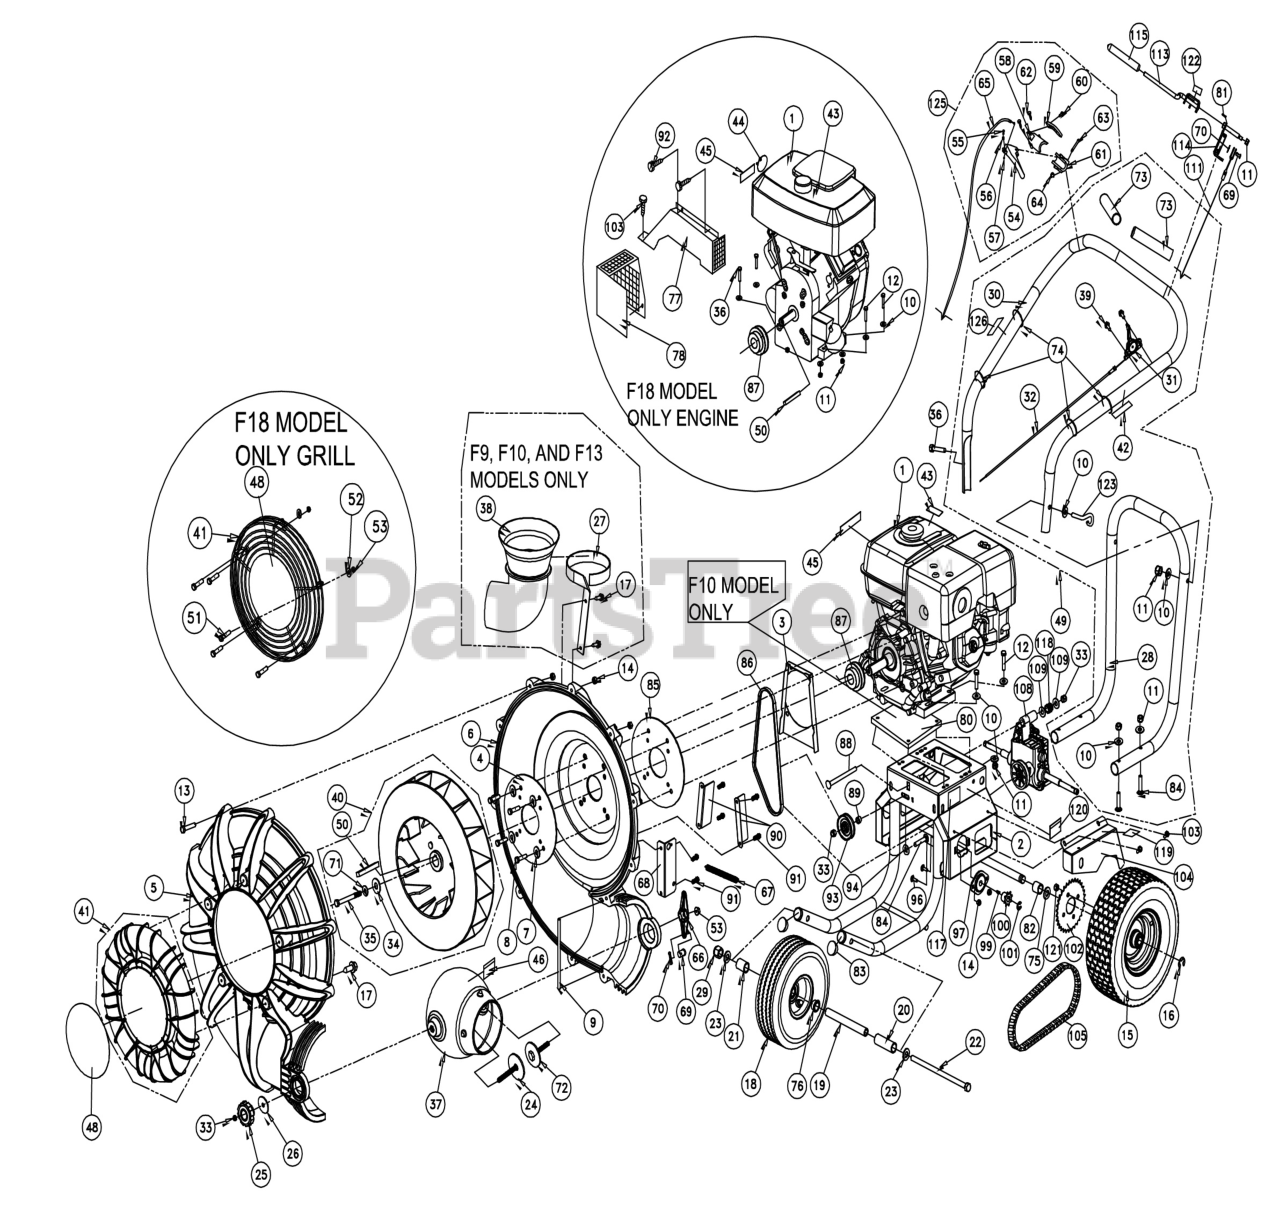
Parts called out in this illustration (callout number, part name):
1	ENGINE HONDA 10PH VANGUARD
2	FORCE FRAME W/LABELS KIT
3	GUARD BELT UPPER FSP
4	SEE: 440330
5	HOUSING FRONT MOLDED
6	HOUSING BACK MOLDED
7	WASHER LOCK 7/16" S/T MED
8	SCREWCAP 3/8"-16X2" HCS ZP
9	ROD HAND STOP
10	WASHER 5/16" FLATWASHER Z/P
11	NUT LOCK 5/16"-18 HEX Z/P
12	SCREWCAP 5/16"-18X2 1/2" HCS ZP
13	SCREWCAP 1/4"-20X1 1/2" HCS ZP
14	NUT WHIZ 1/4"-20 WASH FACE
15	WHEEL & TIRE 13" X 5" PNEU SPROCKET
16	RING RETAINING "E" 3/4"
17	SCREW SM 1/4"X3/4" TYPE A HX WF
18	WHEEL ASSY PNEUMATIC
19	SPACER AXLE FRONT
20	SPACER LH WHEEL FRONT
21	SPACER RH WHEEL FRONT
22	SCREWCAP 1/2"-13 X 9 1/2" HCS ZP
23	WASHER 1/2" SAE Z/P
24	WASHER W/BOLT WA
25	KNOB 3/8-18, SOLID HUB
26	WASHER 2.25 OD X .515 ID X .134 ZP
27	BRACKET EXHAUST FRONT
28	HANDLE LOWER
29	NUT LOCK 1/2"-13 NYLON INSERT
30	HANDLE UPPER
31	CONTROL THROTTLE BLOWER
32	CABLE THROTTLE BLOWER
33	NUT LOCK 3/8-16 LT WT THIN ZP
34	WASHER 1.5 OD X 0.453 ID X 0.5
35	SCREWCAP 7/16-20 X 3 1/2 GR. 8 W/ PATCH
36	SCREWCAP 5/16"-18X2" HCS ZP
37	DIRECTOR CONE 4" W/LABEL
38	DIVERTER FRONT 4" (NEW STYLE)
39	SCREW SELFTAP #10-24 X 3/8"ZP
40	IMPELLER SERVICE KIT FORCE
41	GRILL KIT GEN II
42	LABEL THROTTLE CONTROL
43	LABEL HOT ENGINE
45	LABEL SAFETY PROTECT READ MANUAL
46	LABEL DANGER FLYING DEBRIS
48	LABEL FORCE GEN II SP
49	SEE: 440104-S
50	KEY 1/4" SQ X 3 1/4"
53	NUT LOCK 1/4"-20 HEX Z/P
54	LEVER DIVERTER
55	PIN LATCH DIVERTER
56	SPRING COMPRESSION 0.281 X 0.88
57	RING RETAINING 3/16" E-CLIP
58	SADDLE LOWER DIVERTER
59	PLATE LOCK DIVERTER
60	SCREW PLASTITE #6-19 X 5/8" HWH ZP
61	SADDLE UPPER DIVERTER
62	SCREW PLASTITE #10-14 X 1" HWH ZP
63	PIN PIVOT DIVERTER CONTROL
64	RING RETAINING 5/16"
65	CABLE DIVERTER
66	DIVERTER REMOTE ADAPTER
67	SPRING EXTENSION .468 X 5.25
68	BRACKET DIVERTER FORCE
69	PIN CLEVIS 1/4" X .75"
70	PIN CLIP HITCH 0.051 X 3/4"
71	WASHER LOCK 7/16" S/T MED
72	ADAPTOR MOUNT WA
73	GRIP 1-1/4" ID X 9.5" LONG
75	WASHER .765" ID X 1.25 OD X .06"
76	FORCE WHEEL BEARING .751 ID
80	SPACER PLATE WELDMENT
81	PIN ROLL 1/8" X 1/2" Z/P
82	SPACER REAR WHEEL SP
83	PLUG TUBE INSERT 1.25" O.D.
84	BOLT CARRIAGE 3/8"-16 X 1 3/4" ZP
85	PLATE ENGINE SPACER
86	BELT FORCE SP
87	SPACER HUB 1" ID X 1.25" W/PULLEY
88	BOLT CARRIAGE 3/8-16 X 5" ZP
89	TUBE SPACER 0.625" OD X 0.357" LONG
90	GUARD BELT LOWER FSP
91	SCREW PLASTITE 1/4-10 X 3/4 HWH ZP
93	PULLEY V IDLER 2.5
94	WASHER 1.00" OD X 0.380 SQ HOLE
96	BOLT CARRIAGE 1/4" X 3/4"
97	SEE: 891025-S
99	KEY WOODRUFF 1/8" X 1/2"
100	SPROCKET 8 TOOTH 41B8
101	RING RETAINING 1/2"
102	SPROCKET 32T #43 1.594" BORE
103	SCREW SELF TAP 1/4"-20 X 5/8" HWH TYPE F
104	CHAIN CUARD LH W/LABELS KIT
104	CHAIN CUARD RH W/LABELS KIT
105	CHAIN #43 X 44 PITCHES
108	TRANS SINGLE SPEED W/CLUTCH GENERAL
109	WASHER 3/8"SAE 13/32"X13/16"X1/16"
111	CABLE CLUTCH FORCE SP
113	ARM, CLUTCH CONTROL WA
114	BRACKET CLUTCH CONTROL
115	GRIP CLUTCH CONTROL FSP
117	SEE: 100256
118	SPRING LEVER GZ
119	LABEL OIL CHAIN VQSP
120	LABEL DANGER
121	NUT 5/16-24 SER. HEX WSHR FLNG
122	LABEL CLUTCH DRIVE
123	EYEBOLT, PIGTAIL 5/16"-18 X 1 1/4"
126	FORCE AIM AND SHOOT LABEL
